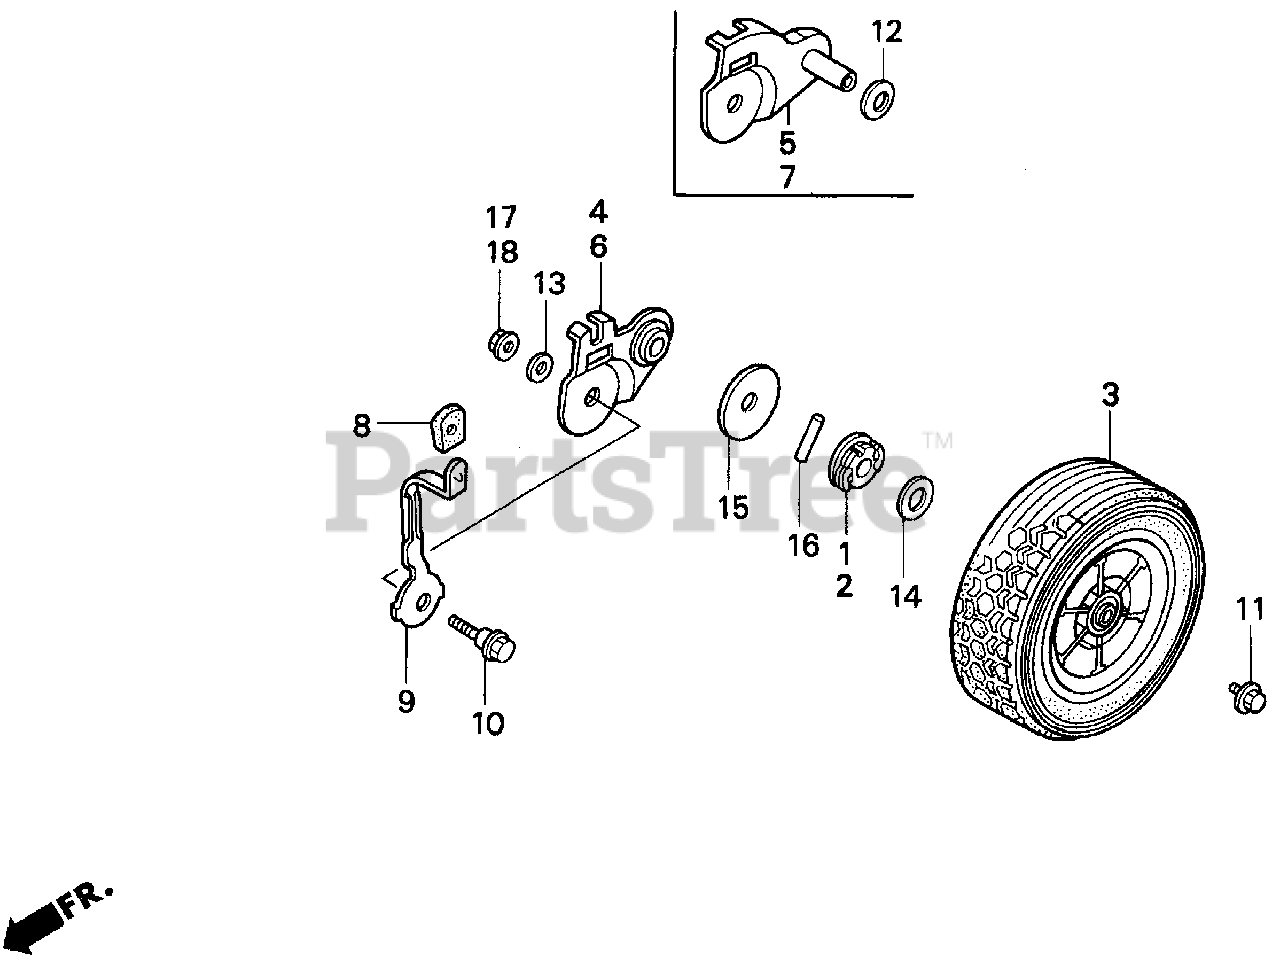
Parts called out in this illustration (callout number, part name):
3	WHEEL (8") *NH31* (MCKINLEY WHITE)
5	ARM C, L. WHEEL ADJUSTER
7	ARM D, R. WHEEL ADJUSTER
8	GRIP, ADJUSTER
9	PLATE, RR. ADJUSTER
10	BOLT, ADJUSTING CENTER
11	BOLT, WHEEL
12	WASHER, WHEEL
13	WASHER A, HANDLE HOLDER SETTING
17	NUT, HEX. (8MM) (RIGHT SIDE)
18	NUT, FLANGE (8MM) (LEFT SIDE)
NI	TIRE (8 INCH)
